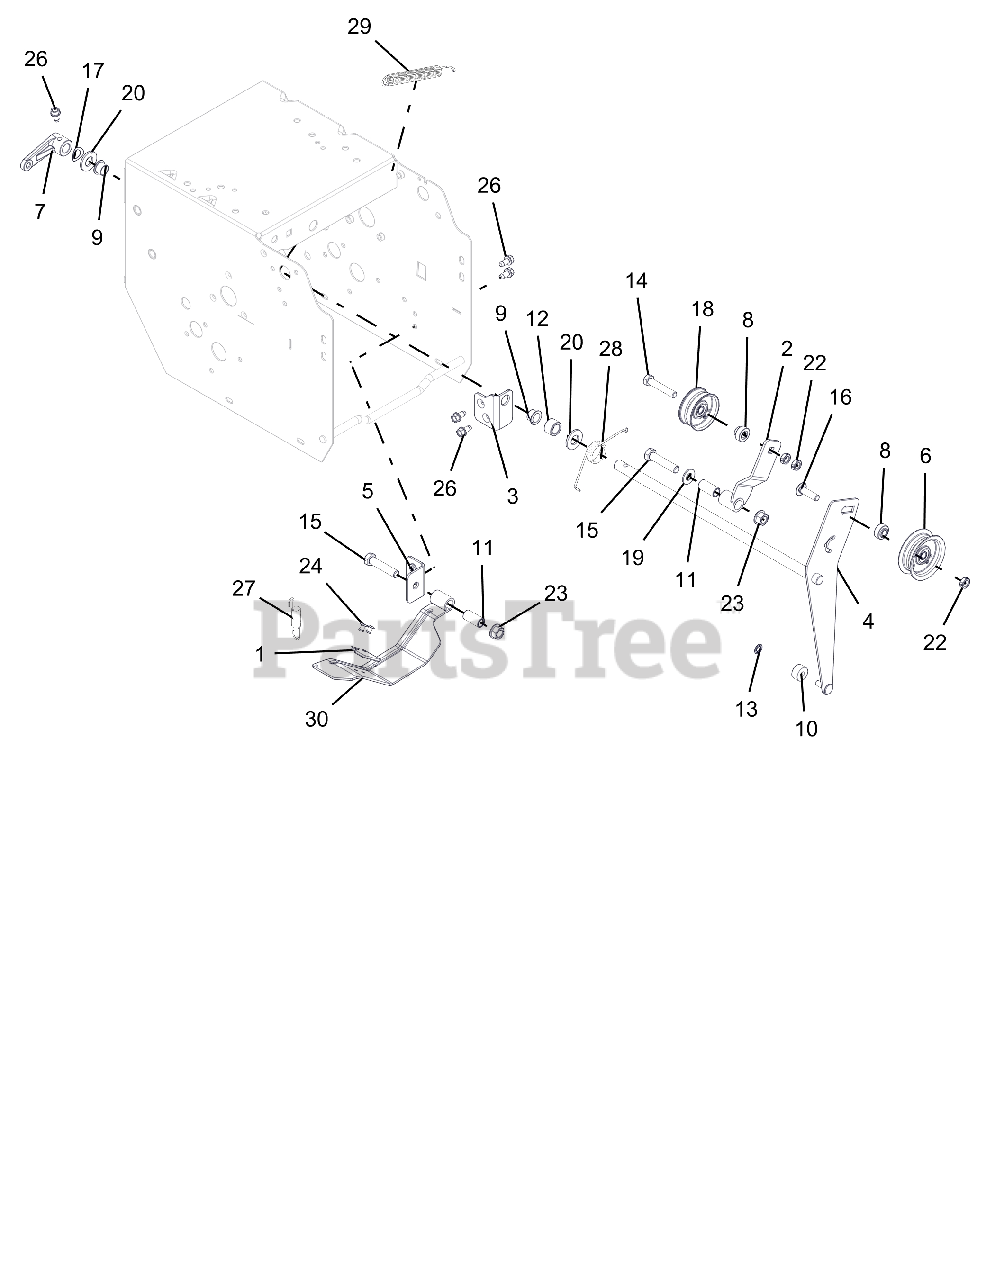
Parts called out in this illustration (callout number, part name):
1	PAD, BRAKE
2	ARM, TRACTION IDLER
3	BRACKET, MOUNT - IDLER ARM
4	WELDMENT, ATTACHMENT IDLER ARM
5	BRACKET, MOUNT - BRAKE
6	IDLER, FLAT - 2.00"
7	ARM, CLUTCH - ATTACHMENT
8	BSHG-SLV .325X.49X1.56
9	BUSHING, POLYLINER-.50 SPLIT
10	BSHG,SLV .265 X .625 X .375
11	BSHG-SLV .385X.500X1.045
12	BSHG-SLV .510X.751X.475
13	RG-RTNG-EXT .250X.010
14	@BLT-HEX .31-18X1.75 GR5 YWZC
15	@BLT-HEX .38-16X1.75 GR5 YWZC
16	BLT-RDHDSQSHNK.31-18X1.13 G5YZ
17	WSHR-WAVE .50X.75X.015 .13FRHT
18	IDLER, FLAT - 1.875"
19	@WSHR-FL-STL.406X.812X.065 YWZ
20	@WSHR-FL-STL.531X1.06X.095YWZC
22	@NUT-LK-CTR-JAM .31-18 YWZC
23	@NUT-LK-TOP-FLG .38-16 YWZC
24	RVT-POP .187 YZ
26	SCR-TAP .25-20X.50 HWH TR YWZ
27	SPRING-EXT .437 X .438 X 2.64
28	SG-TORS .075 X .955
29	SPRING, EXTENSION
30	BRAKE ARM W/PAD
